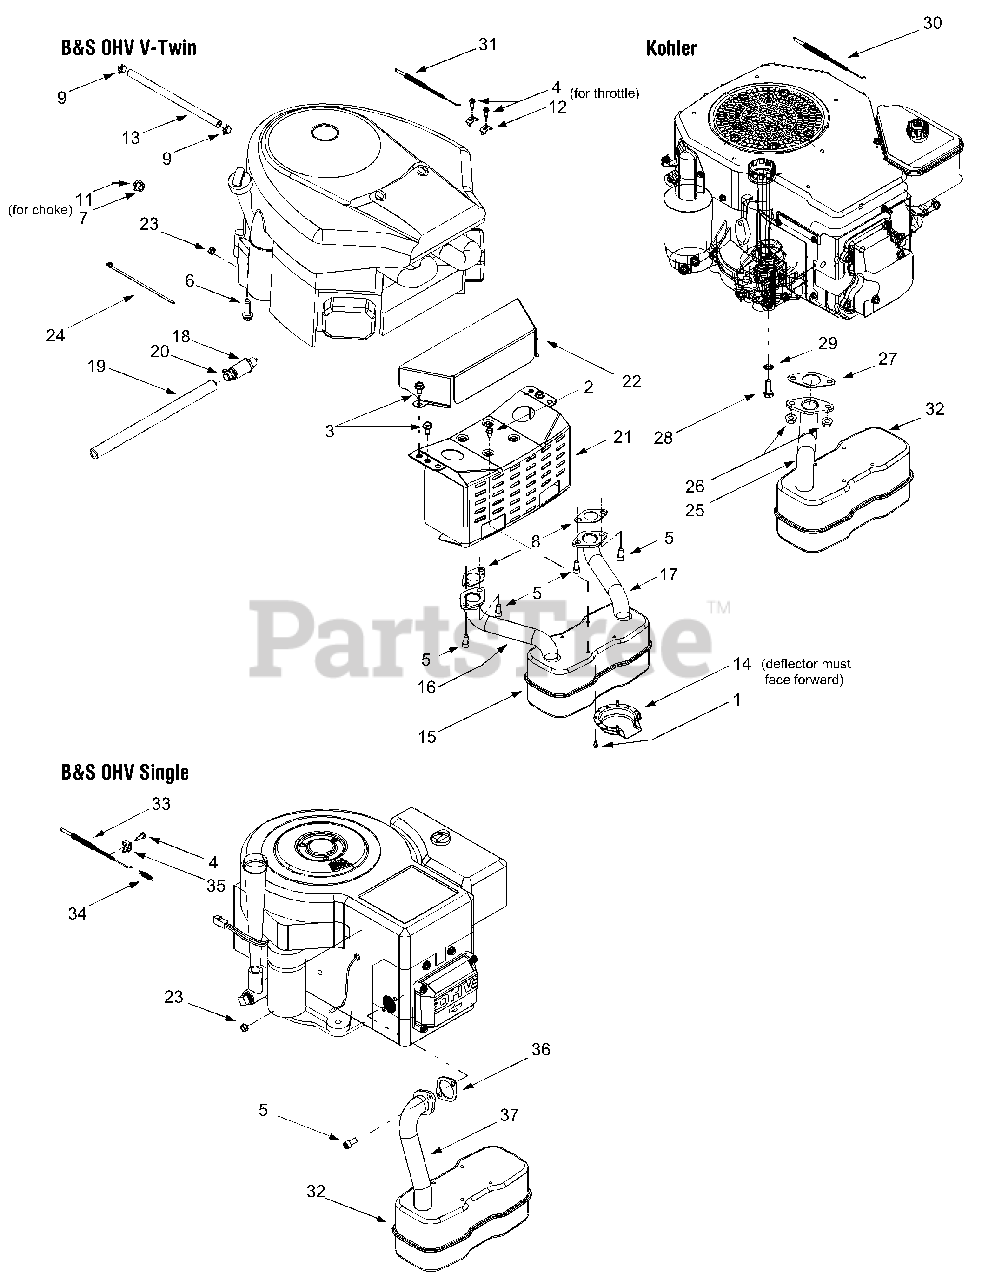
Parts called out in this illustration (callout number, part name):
1	Self-tapping Screw, #8-18 x.50
2	Self-tapping Screw, 1/4-20 x.50
3	Self-tapping Screw, 5/16-18 x.625
4	Screw, #10-32 x.625
5	Socket Cap Screw, 5/16-18 x.625
6	Self-tapping Screw, 3/8-16 x 1.25
7	Hex Nut, 3/8-16
8	Exhaust Gasket
9	Hose Clamp
10	Casing Clamp
11	Lock Washer,.406 x.875 x.059
12	Casing Clamp
13	Fuel Line Hose
14	Muffler Deflector
15	Muffler, Twin Inlet
16	RH Exhaust Pipe
17	LH Exhaust Pipe
18	Oil Drain Valve
19	Oil Drain Hose
20	Oil Drain Cap
22	Engine Heat Shield
23	Hex Sems Nut, 1/4-20
24	Cable Tie
25	Exhaust Pipe
26	Flange Nut, 8mm
27	Exhaust Gasket
28	Hex Cap Screw, 8mm
29	External Lock Washer
30	Throttle Cable
31	Throttle Cable
32	Muffler, Single Inlet
33	Throttle Cable
34	Extension Spring, .275 x 1.25
35	Casing Clamp
36	Exhaust Gasket
37	Exhaust Pipe
